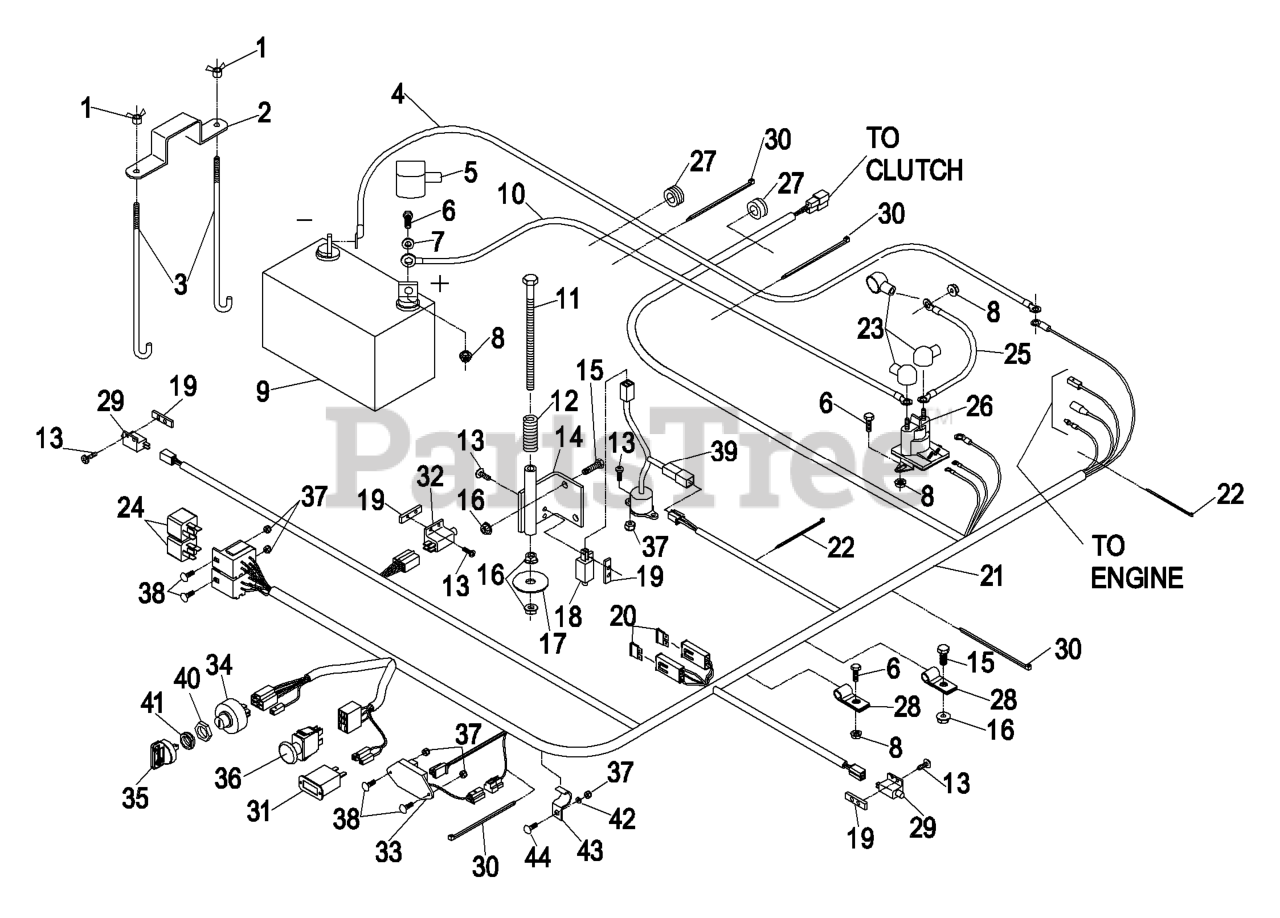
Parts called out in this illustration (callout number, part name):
1	WINGNUT
2	STRAP-HOLDDOWN
3	BOLT-HOLDDOWN
4	CABLE-GROUND, NEGATIVE
6	SCREW-HH
7	WASHER-FLAT
11	SCREW-HH
12	SPRING-SWITCH, SEAT
13	SCREW-PPH
14	BRACKET-SWITCH, SEAT
15	SCREW-HH
18	SWITCH-CLOSED, NORMALLY
19	PLATE-TAPPED
20	FUSE-BLADE TYPE, 20 AMP
21	HARNESS-WIRE
22	TIE-CABLE
23	INSULATOR-SOLENOID
27	GROMMET
28	CLIP-LOOM
29	SWITCH-OPEN, NORMALLY
30	TIE-PLASTIC
31	METER-HOUR
33	MODULE-DELAY, SEAT
35	KEY-IGNITION
37	NUT-LOCK, NI
38	BOLT-CARR
40	NUT-SWITCH, IGNITION
41	SEAL-SWITCH, IGNITION
42	WASHER-FLAT
43	CLIP-HALF, LOOM
44	BOLT-CARR
